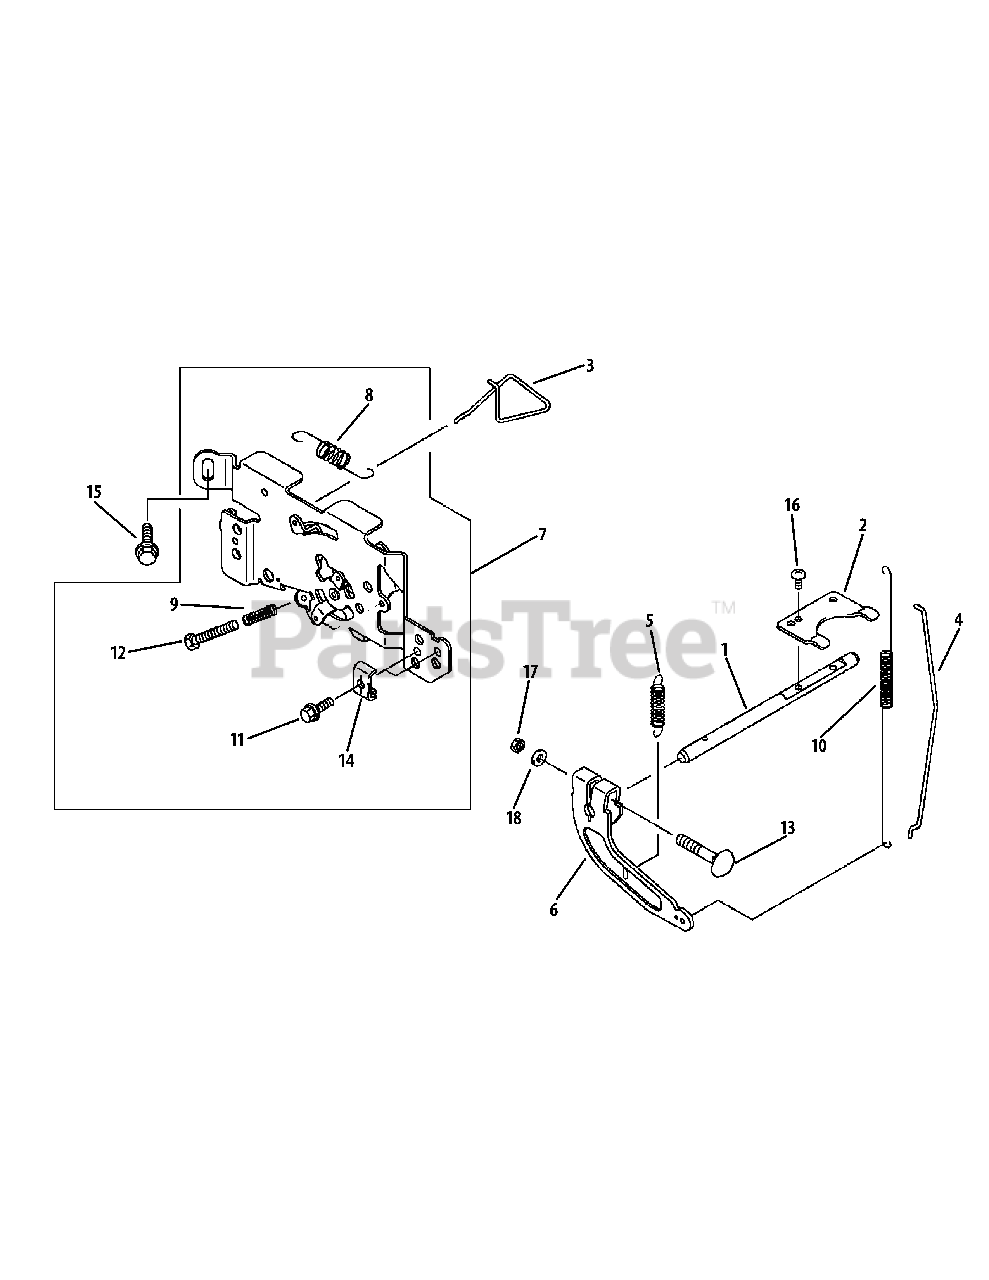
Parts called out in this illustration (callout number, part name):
1	Shaft
3	Choke Link
4	Link
5	Governor Spring
7	Control Panel
8	Spring
13	Bolt, 6 x 35
15	Bolt, 6 x 12
16	Pan Screw, 4 x 8
17	Hex Nut
18	Plain Washer
